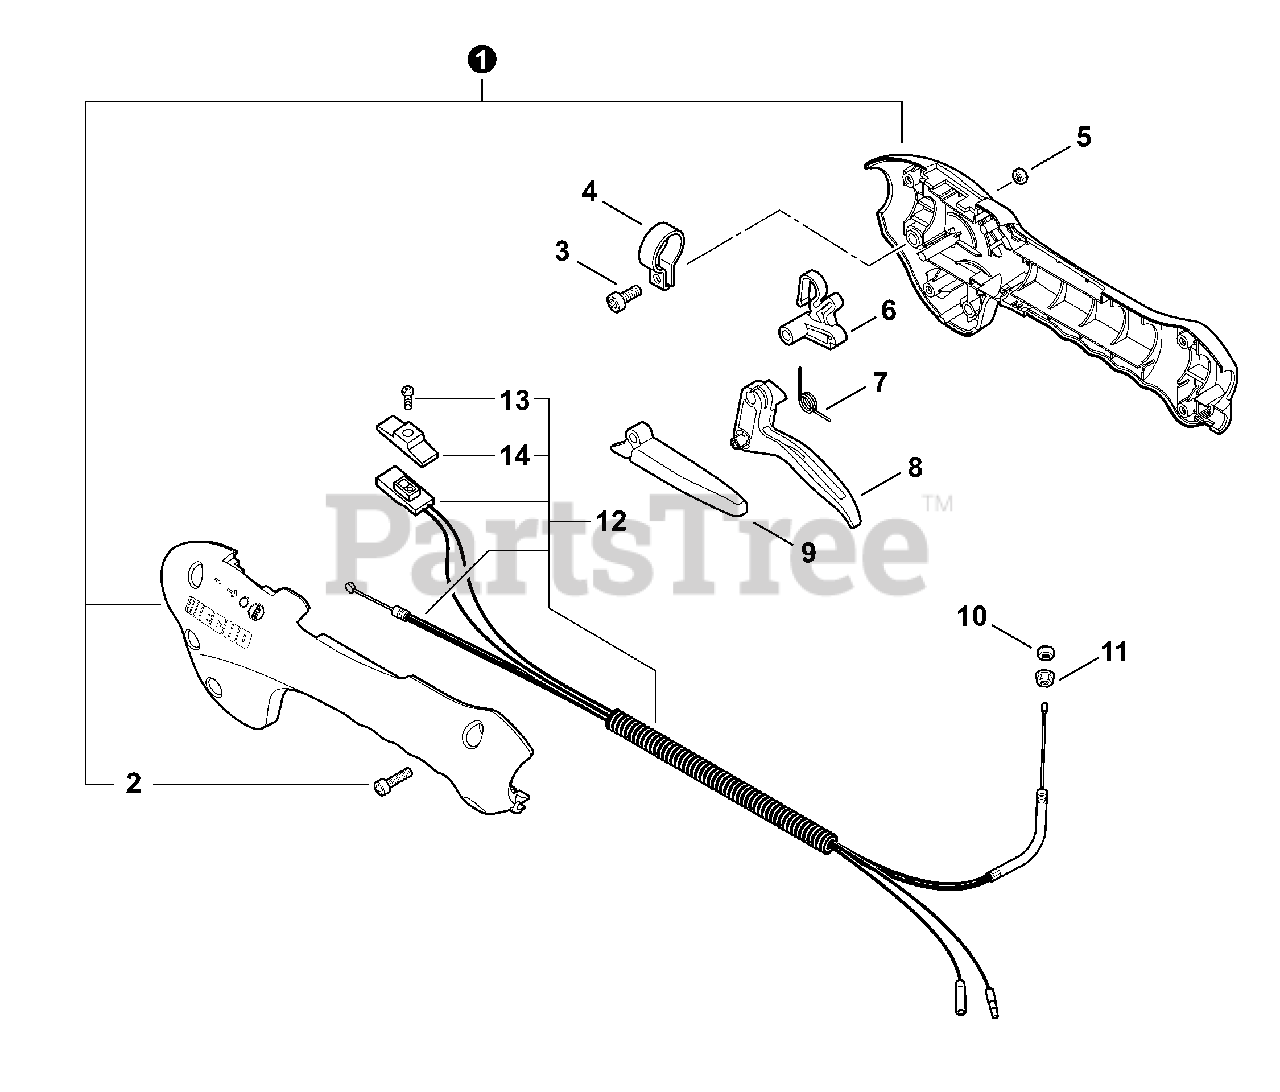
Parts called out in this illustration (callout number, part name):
1	CONTROL HANDLE ASY
2	SCREW - 4×16 -- TAPPING
3	SCREW - 5×16
6	LOCKOUT, TRIGGER
7	SPRING, TRIGGER
8	TRIGGER, THROTTLE
9	LEVER, LOCKOUT
11	NUT - 6 -- FLANGE
12	CONTROL CABLE ASY
13	SCREW - 3×10
